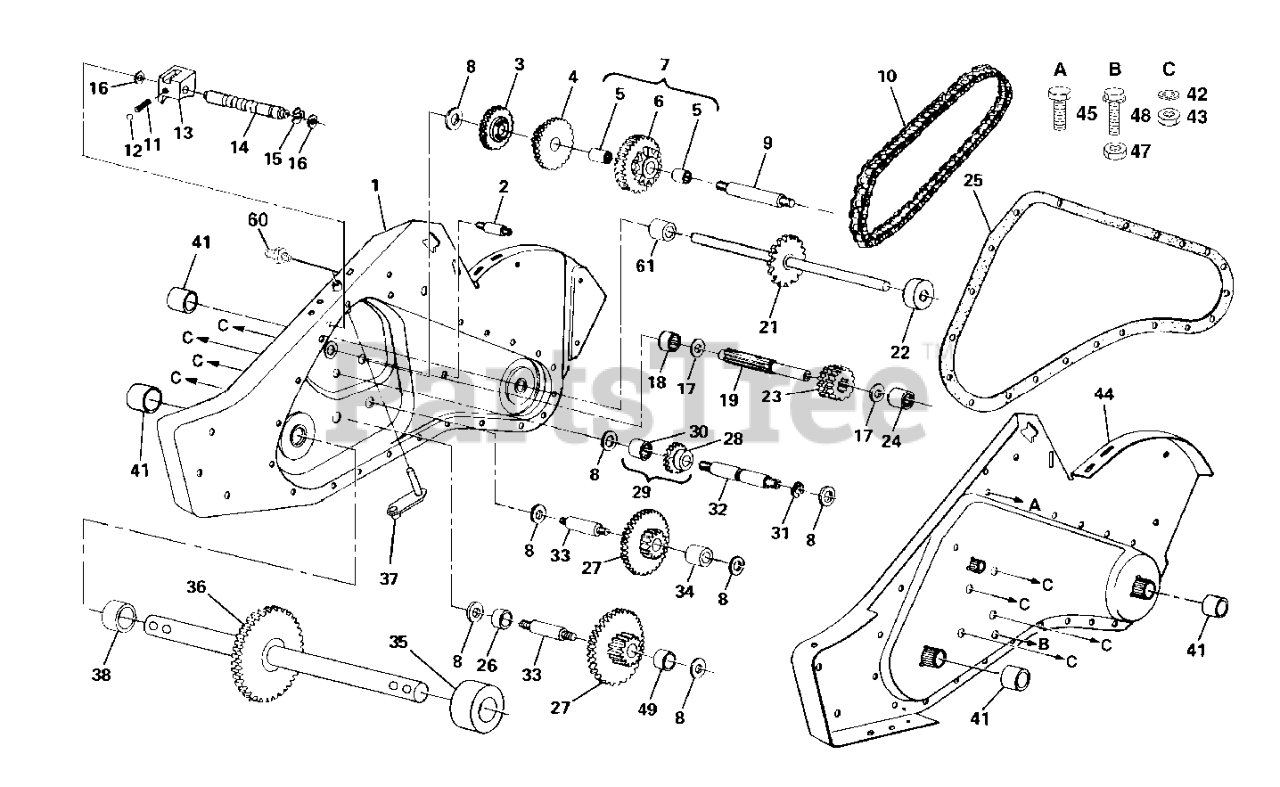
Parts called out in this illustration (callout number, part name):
1	GEARCASE ASM.RH.W/BEARING 2002
2	SPACER.GEARCASE
3	GEAR.REVERSE.8HP
5	NEEDLE BEARING
6	SPROCKET ASMBLY, TINE
7	SPROCKET ASMBLY W/BEARINGS
9	SHAFT.REDUCTION.TILLER
10	CHAIN.ROLLER.TILLER
11	SPRING-SHIFT CRT
12	STEEL BALL KIT
13	SHIFT FORK TI
14	SHAFT.SHIFT.1.00 PINION
16	WASHER, SEAL (2 2)
17	THRUST WASHER
18	BEARING TI
19	SHAFT INPUT
21	SHAFT.ASM.TINE.21
22	SPACER 1.008X1-3/4X.645
23	GEAR.PINION.INPUT
24	NEEDLE BRNG LT
25	GASKET.GEARCASE.TILLER.8HP
27	GEAR, CLUSTER CRT
28	REVERSE GEAR
29	GEAR ASMBLY, REVERSE IDLER
30	NEEDLE BEARING TI
32	SHAFT, REVERSE IDLER
33	SHAFT, REDUCTION
34	SPACER.765 X 1.12 X .380.
35	SPACER, GROUND DRIVE RH
36	SHAFT ASSY CRT
37	BRACKET ASM.SHIFT.CRT
38	SPACER, GROUND DRIVE
41	SEAL ASM, OIL
42	LOCKWASHER
43	NUT.ASF.HEX.7/16
44	GEARCASE ASM.LH.W/BEARING 2002
45	BOLT.5/16HEX.WHS.HD
48	SCREW 5/16-18X4
60	FITTING.GREASE.TAPERED
61	SPACER.1.015 X 1.50 X .765
